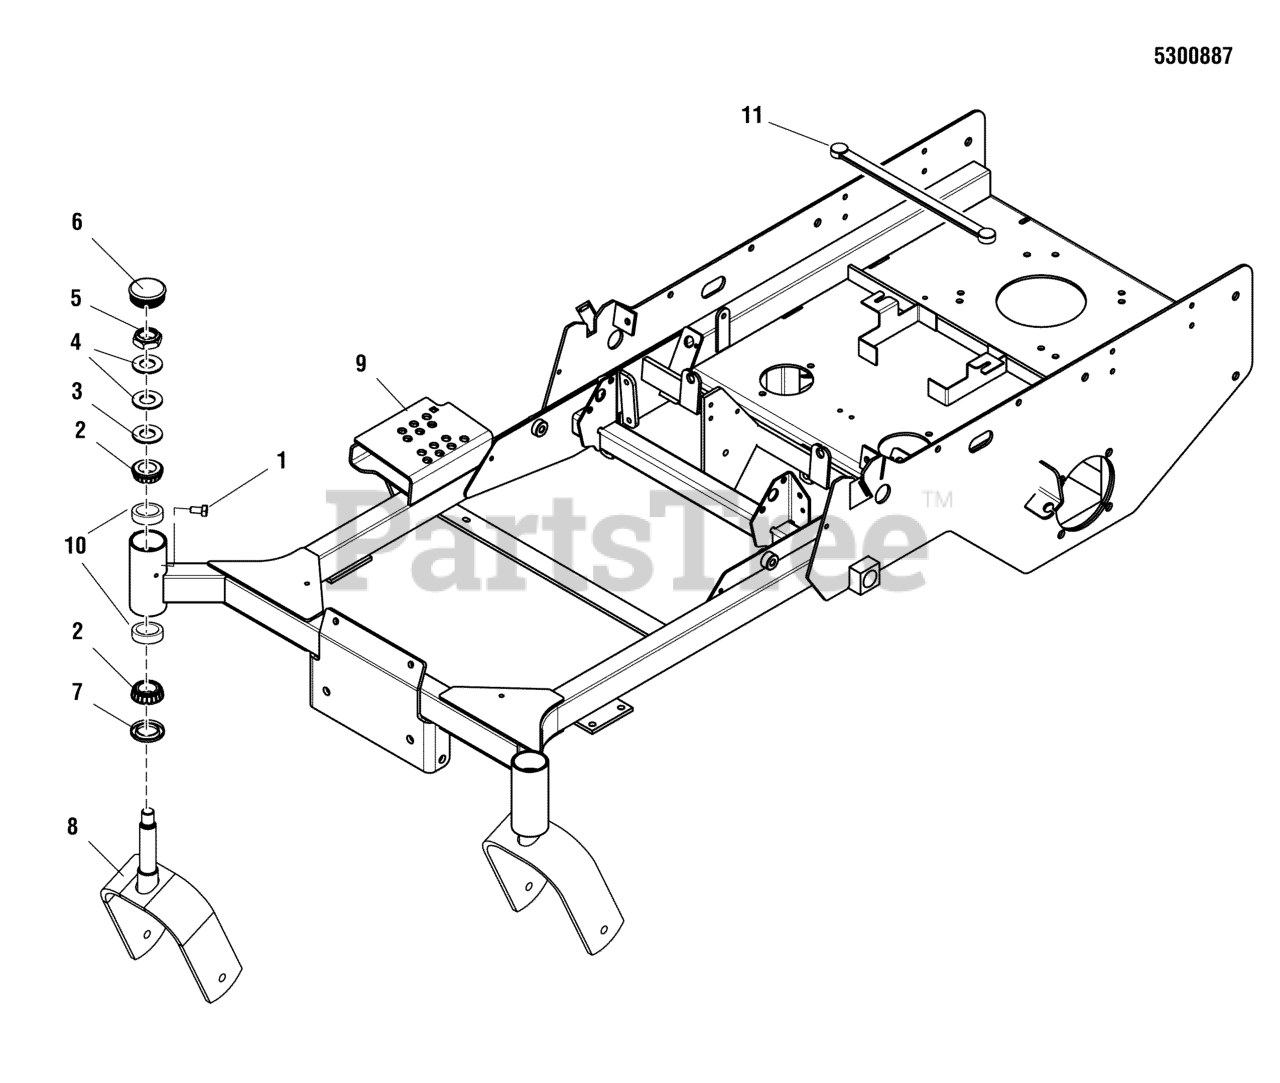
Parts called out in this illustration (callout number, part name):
1	BOLT, 1/4-28 X 1/2, GD5 YZ
2	BEARING, TAPERED ROLLER, 1"
3	WASHER, 3/4 SAE
4	WASHER, BELLEVILLE - 1.500 X .755
5	NUT, 3/4-16, HEX JAM NYLON LOCK
6	CAP, GREASE, LOW PROFILE
7	SEAL, GREASE
8	WELD, CASTER YOKE - RED
9	WELD, MAIN FRAME, SNP 2552 - RED
10	CUP, BEARING (SV)
11	STRAP-BLACK RUBB
